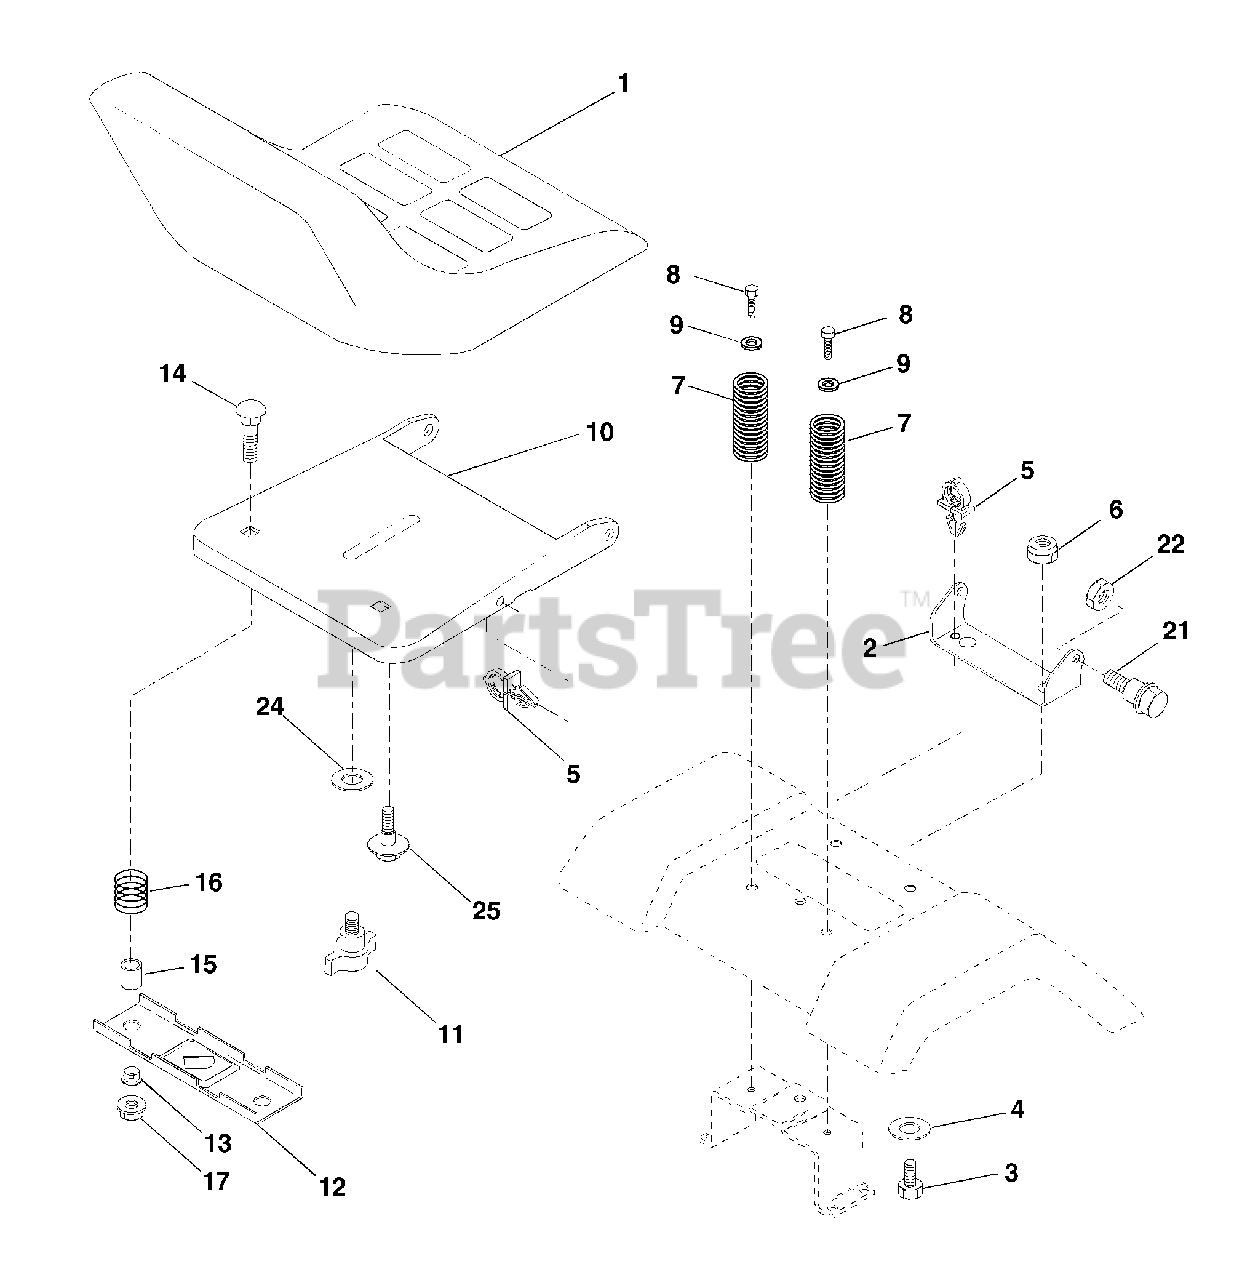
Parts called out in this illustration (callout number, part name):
1	Seat
2	Bracket Pivot Seat 8 720
3	Bolt Fin Hex 3/8-16 Unc X 1
4	Washer 13/32 X 1 X 10 Ga
5	Clip Push-In
6	Nut Hex w/Ins. 3/8-16 Unc
7	Spring Seat Cprsn 2 250 Blk Zi
8	Screw 3/8-16 X 1.5
9	Washer 13/32 X 1 X 14 Ga.
10	Pan Seat
11	Knob Seat
12	Bracket Mounting Switch
13	Bushing Snap Blk Nyl 50 Id
14	Bolt Rdhd Sqnk 1/4-20x1-1/2
15	Spacer Split 28x 88
16	Spring Cprsn
17	Nut Lock 1/4 Lge Flg Gr 5 Zinc
21	Bolt Shoulder 5/16-18 Unc
22	Nut Hex Lock W/Ins 5/16-18
24	Washer 17/32 X 1-3/16 X 12 Ga.
25	Bolt Shoulder 5/16-18 X 62
